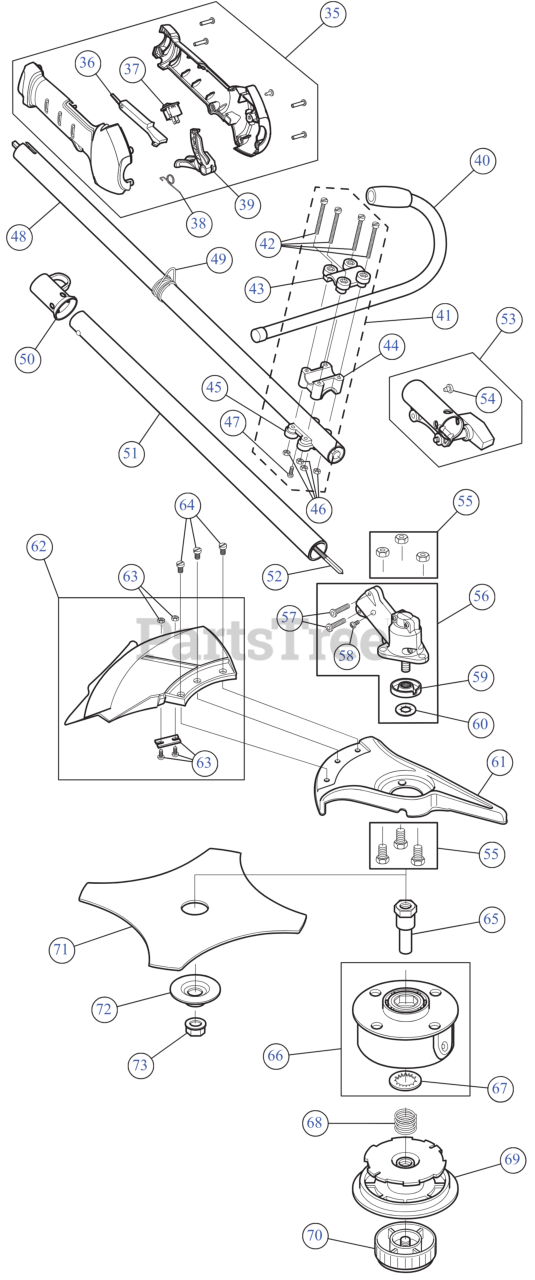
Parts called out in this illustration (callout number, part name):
35	THROTTLE GRIP ASSEMBLY
36	LEVER LOCK OUT
37	SW, MOMENTARY ON/O
38	SPRING TRIG
39	THROTTLE TRIGGER
40	HANDLE ASSEMBLY-JAY
41	HANDLE BRACKET ASSEMBLY
42	CLAMP SCREW
43	HANDLE UPPER CLAMP
44	HANDLE MIDDLE CLAMP
45	HANDLE LOWER CLAMP
46	NUT-CLAMP
47	SCREW, 8-32 x .312 P
48	BOOM ASSEMBLY UPR
49	CLAMP-SHOULDER STR
50	HANGER
51	ASSEMBLY, LOWER DRIVE S
52	LOWER DRIVE SHAFT
53	COUPLER ASSEMBLY
54	SCREW, 10-32X.250 TA
55	SCREW SET-GUARD MT
56	GEARBOX ASSEMBLY
57	SCREW #
58	SCREW, 8-32 x .312 P
59	SPACER-GEARBOX
60	PALNUT:3/8" DIAM
61	SHIELD-BLADE CAST
62	SHIELD ASSEMBLY WITH BLADE
63	BLADE ASSEMBLY
64	SCREW-GUARD MTG PK
65	SHAFT-SPOOL
66	SPOOL ASSEMBLY-OUTER
67	RETAINER .968 OD
68	SPRING-SPOOL
69	REEL-INNER SPOOL 3000 STRG TRM
70	KNOB ASSEMBLY-BUMP 3000 STRG TRM
71	BLADE 4-TOOTH
72	WASHER-BLADE CLAMP BRUSH CUT
73	BLADE LOCK NUT
